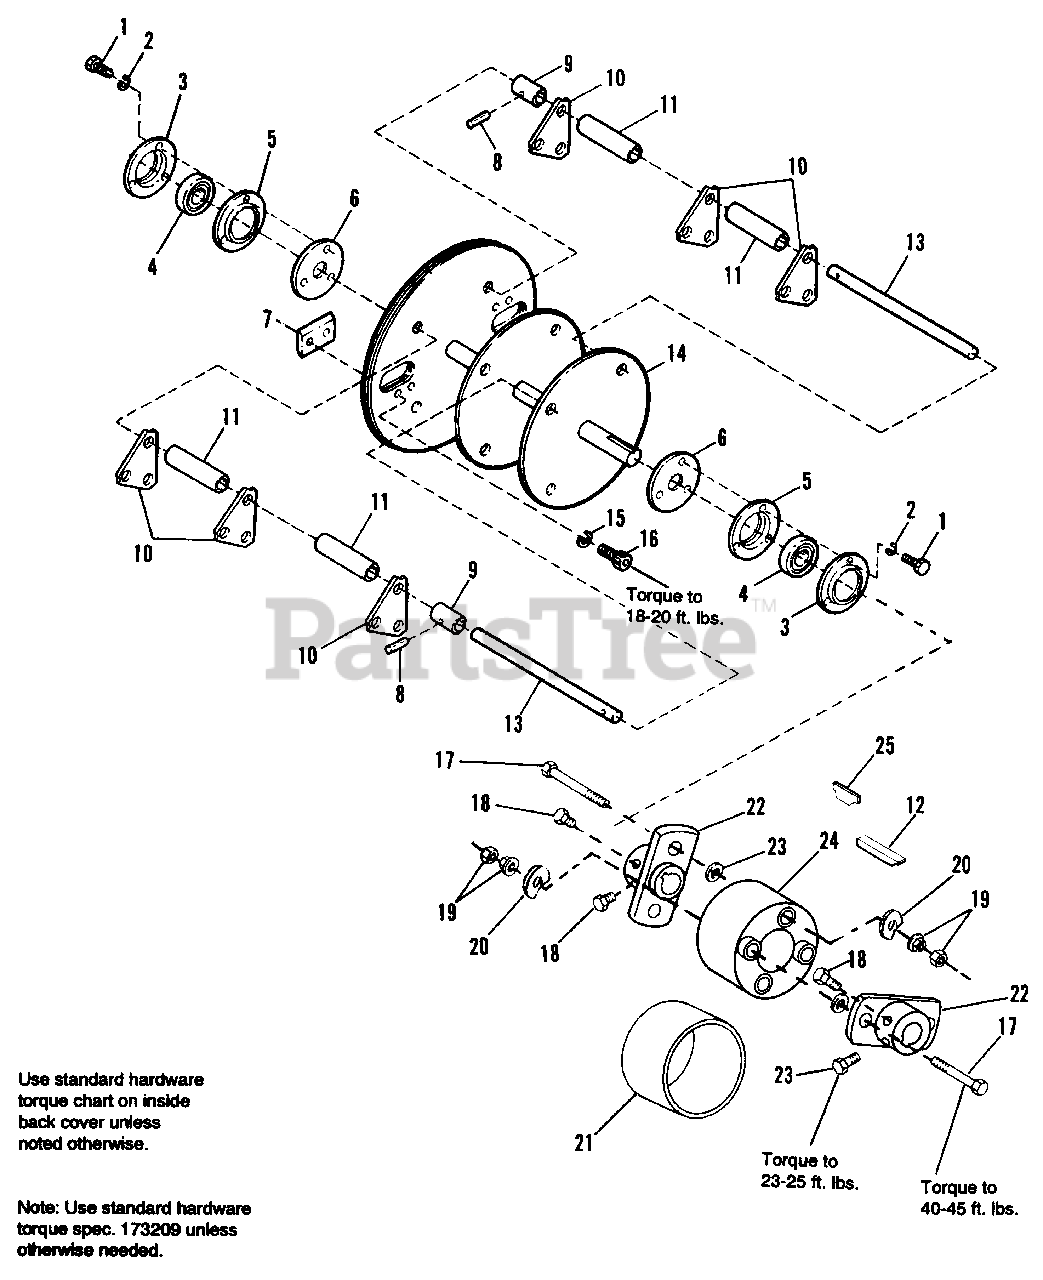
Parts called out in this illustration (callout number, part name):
1	CAPSCREW, Hex, 5/16-18 x 5/8, Gr. 5
2	LOCKWASHER, 5/16
3	FLANGE, Bearing w/Zerk Fitting
4	BEARING, Cartridge
5	FLANGE, Bearing
6	GUARD, Bearing
8	ROLL PIN, 3/16 x 3/4
9	SPACER, Short, 17/32 x 3/4 x 1-1/4
10	HAMMER, Triangle
11	SPACER, Long, 17/32 x 3/4 x 2-1/2
12	KEY, Square, 1/4 x 1/4 x 2-1/4
13	SHAFT, Hammer, 1/2 x 7-9/16
14	ROTOR ASSY.
15	LOCKWASHER, 5/16
16	CAPSCREW, 5/16-18 x 7/8
17	CAPSCREW, Hex, 3/8-16 x 2-3/4, Gr.8
18	CAPSCREW, Hex, Socket Hd., 5/16-18 x 3/4, Gr. 8
19	NUT, Hex, Lock, 3/8-16
20	WASHER, Special, 13/32 x 1-1/2 x 1/8
21	SLEEVE, Coupler
22	HUB & PLATE ASSY.
23	WASHER, Plain, 13/32 x 1 x 1/8
24	COUPLER, Drive
25	KEY, Hi-Pro
